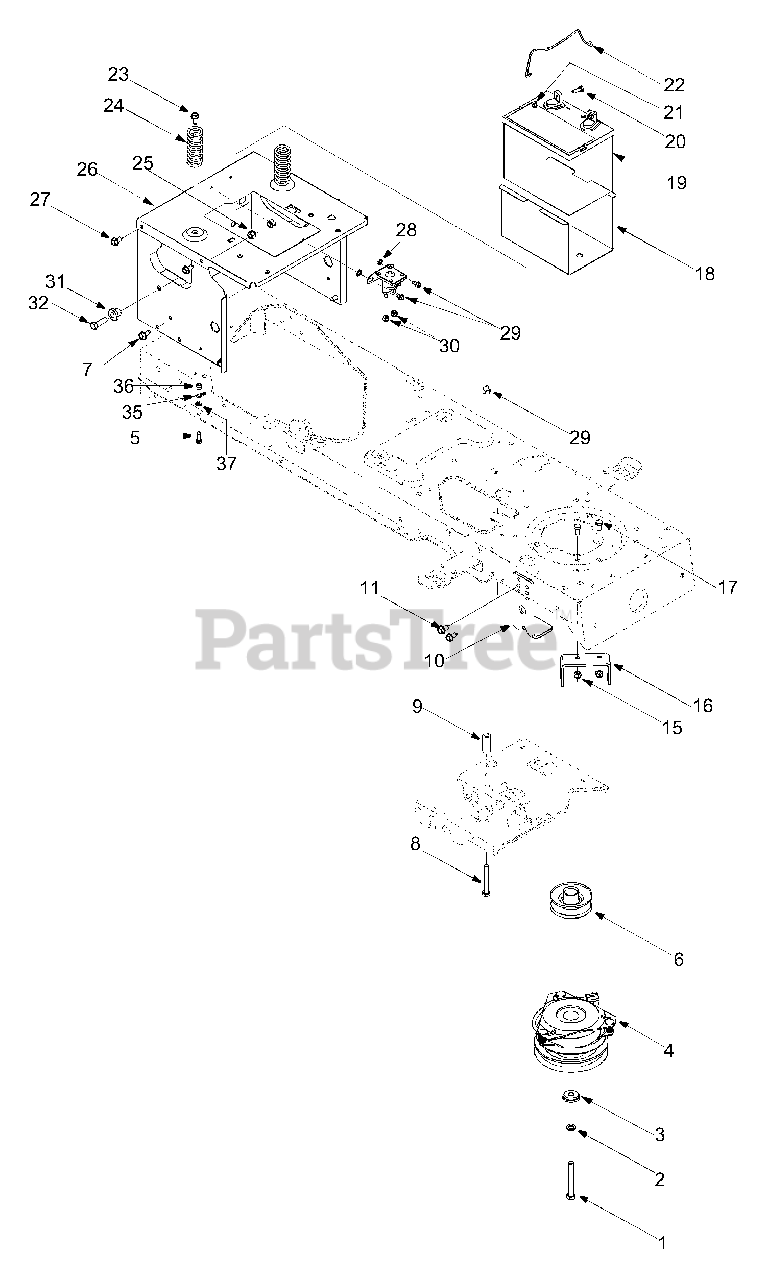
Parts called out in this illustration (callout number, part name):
1	Hex Bolt 7/16-20 x 3.25
2	Lock Washer
3	Shoulder Spacer
4	PTO Clutch
5	Shoulder Screw 3/8-16
6	Engine Pulley
7	Hex Lock Nut 1/4-20
8	Hex Bolt 3/8-16 x 2.5
9	Spacer
11	Screw 5/16-12 x 0.75
12	Hex Lock Nut 5/16-18
17	Carriage Screw
18	Sems Nut
19	Battery Hold-Down Rod
20	Screw 5/16-12 x 0.75
21	Compression Spring
22	Lock Nut
25	Lock Washer
26	Self-tapping Screw 1/4-20 x 0.5
27	Lock Nut 1/4--20
28	Shoulder Spacer
29	Hex Bolt 3/8-16 x 1.25
30	Screw 5/16-12
31	Self-tapping Screw 1/4-20 x 0.75
32	Ground Wire (For reference only)
